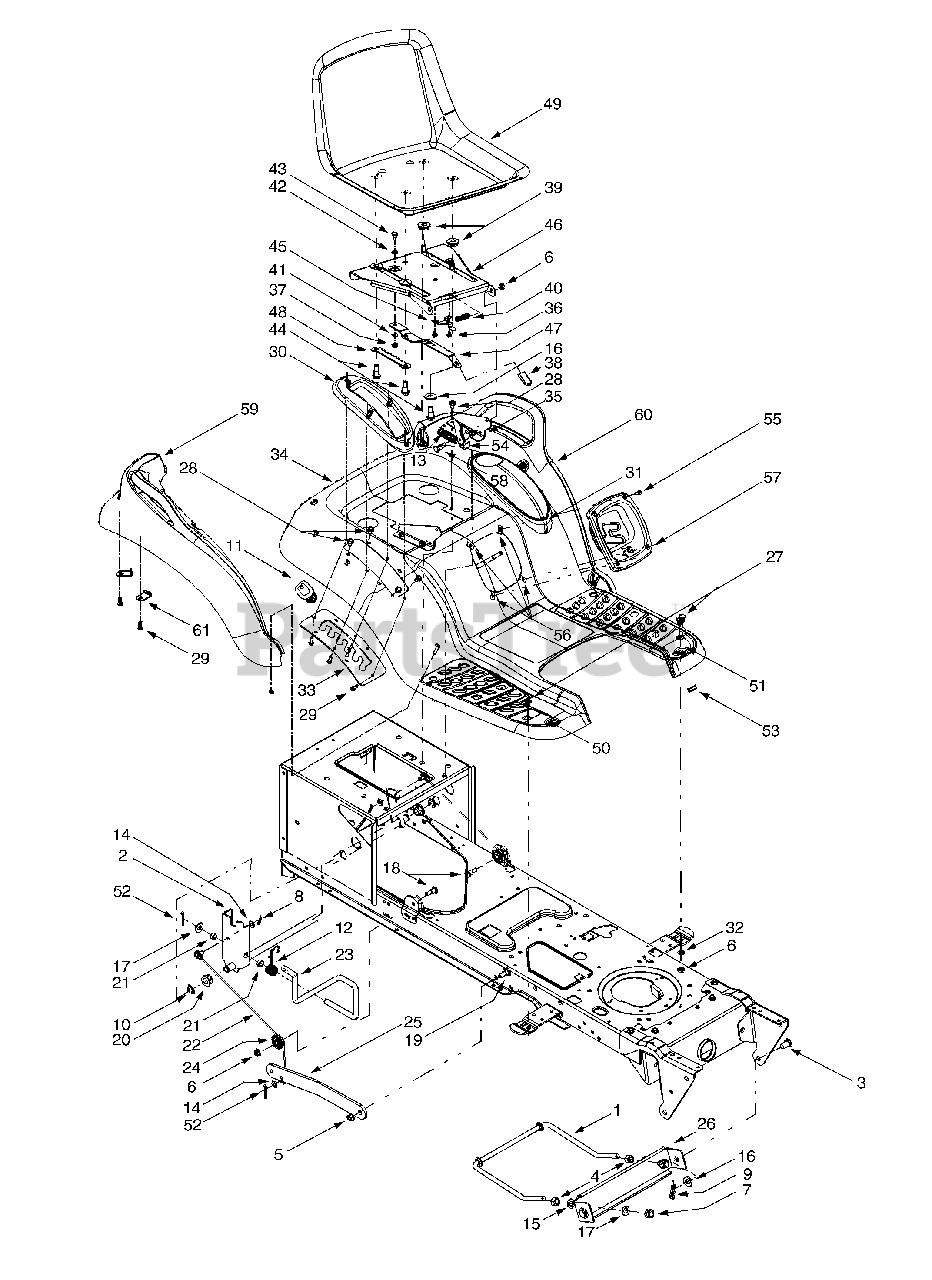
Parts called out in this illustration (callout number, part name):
1	Deck Stabilizer Rod (Model B809H)
2	Lift Shaft Assembly (Model B809H)
3	Clevis Pin, .5 x .78
4	Hex Nut, 1/2-13
5	Flange Lock Nut, 3/8-16
6	Flange Lock Nut, 5/16-18
7	Hex Nut, 1/2-13
8	Internal Cotter Pin
9	Internal Cotter Pin
11	Handle Grip
12	Torsion Spring
13	Extension Spring, .84 x 4.6
14	Flat Washer, 5/16
15	Lock Washer, 1/2
16	Flat Washer, .31 x 1.062 x .134
17	Flat Washer, .51 x 1.12 x .06
18	Hex Cap Screw, 5/16-18 x .62
19	Shoulder Screw, 3/8-16
20	Hex Flange Bearing
21	Snap Flange Bearing
22	Lift Cable, 16.16
23	Lift Handle
24	Roller Pulley
27	Carriage Bolt, 5/16 x .62
28	Self-tapping Screw, 5/16-18 x .625
29	Self-tapping Screw, 1/4-15 x .75
30	Lift Lever Cover
31	Cover w/ Cup Holder
32	Flat Washer, .349 x 1.0 x .063
36	Screw, #10-16 x .375
37	Hex Flange Lock Nut, 1/4-20
38	Seat Adjuster Grip
40	Compression Spring, .41 x 1.5
41	Spring Washer, .265 x .562 x .025
42	Flat Washer, .344 x .62 x .03
43	Shoulder Screw, .340 x .285,1/4-20
44	Shoulder Screw, .50 x .50, 3/8-16
45	Seat Stop
48	Seat Adjustment Selector
49	High Back Seat w/ Drain Holes, Black
50	RH Foot Pad
51	LH Foot Pad
52	Cotter Pin
53	Trim Strip
54	LH Seat Lift Bracket
55	Phillips Pan Screw, 1/4-20 x .75
56	U-type Speed Nut, 1/4-20
57	Shift Lever Cover
58	Shoulder Screw, .437 x .286
59	RH Fender Flare
60	LH Fender Flare
61	Fender Clips
